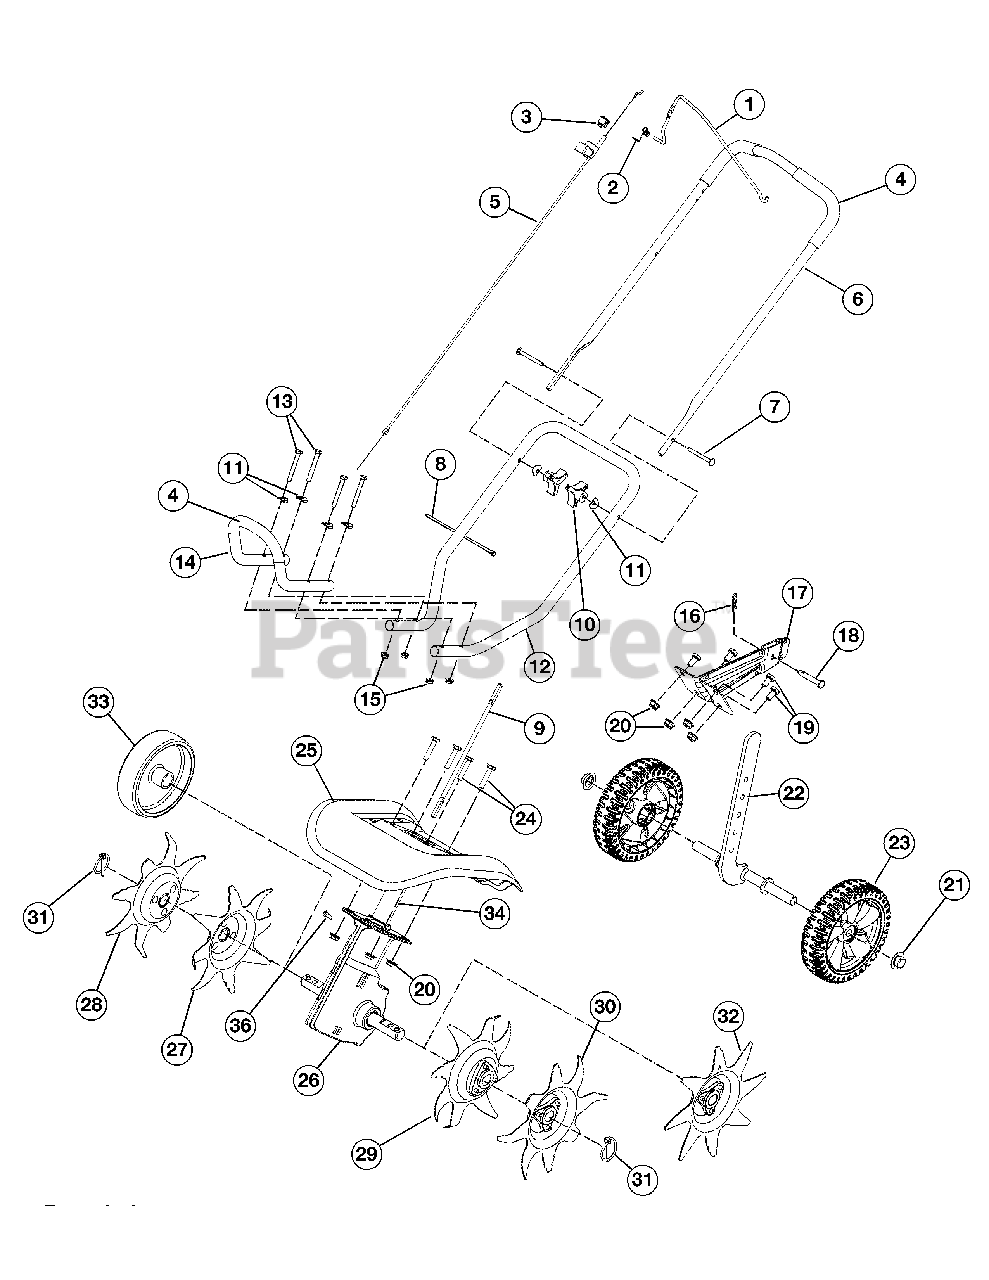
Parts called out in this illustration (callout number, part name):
1	Trottle Control
2	Torsion Spring
3	On/Off Switch
4	Foam Grip
5	Throttle Cable
6	Upper Handle
8	Cable Tie
9	Flex Shaft
11	Saddle Washer
12	Lower Handle
13	Screw
14	Front Handle
15	Lock Nut
16	Cotter Pin
17	Tailpiece Bracket Assembly
18	Clevis Pin
19	Cap Screw
20	Lock Nut
21	Cap Push
22	Wheel Support Bracket Assembly
23	Wheel
24	Cap Screw
25	Tine Shield
26	Gear Box Assembly
27	Inner Tine (right side)
28	Outer Tine (right side)
29	Inner Tine (left side)
30	Outer Tine (left side)
31	Click Pin
32	Edger Tine
33	Edger Wheel
34	Drive Shaft Housing
35	Anti Rotation Screw
